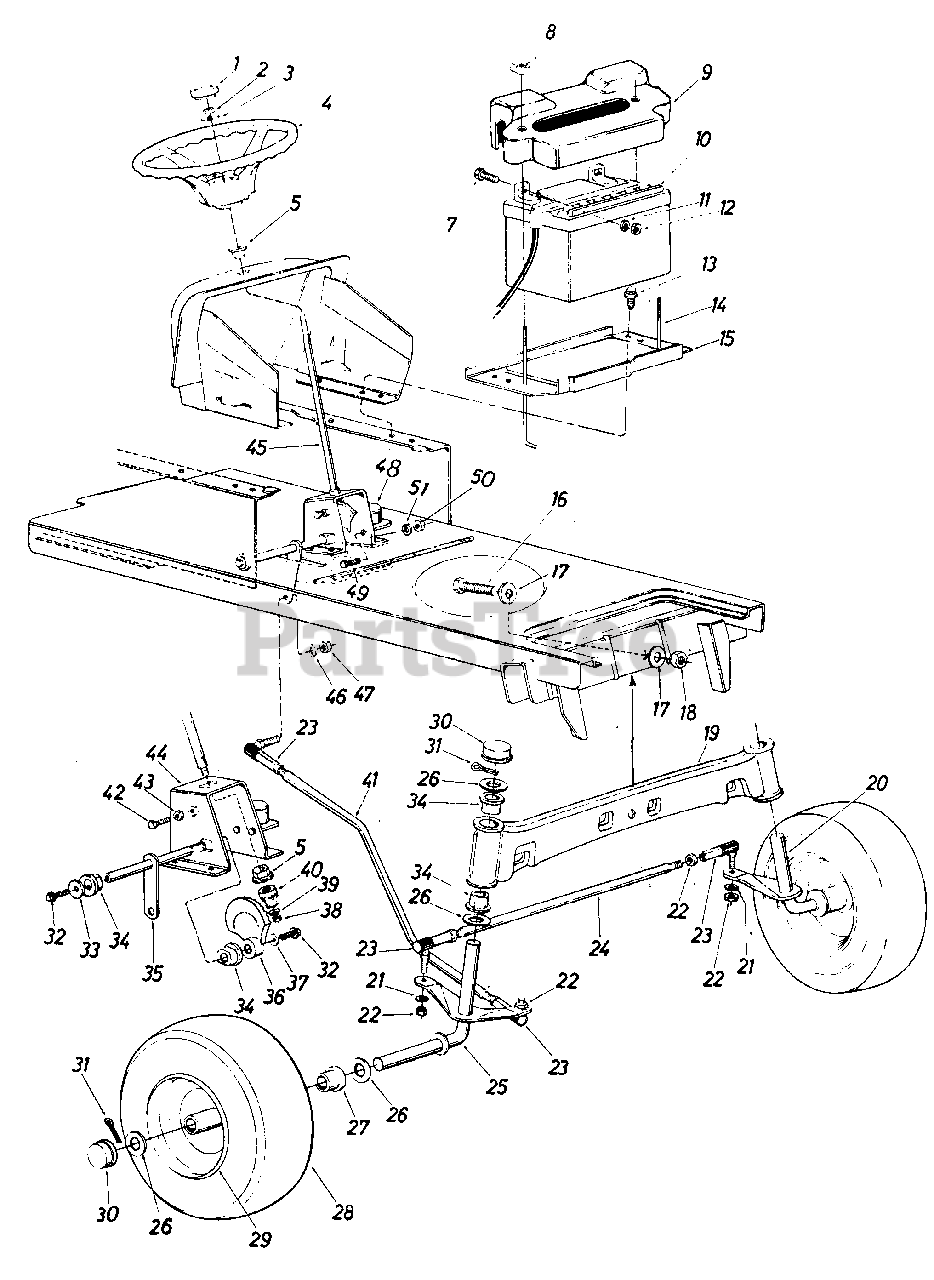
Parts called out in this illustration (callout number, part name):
1	Steering Wheel Cap
2	Hex Cent. L-Nut 5/16-18 Thd.
3	Bell-Wash. 5/16" I.D. x .87" O.D. x .060
4	Steering Wheel
5	Plastic Hex Bearing 5/8" I.D.
7	Hex Scr. 1/4-20 x .62" Lg.
8	Wing Nut Plastic 1/4-20 Thd.
9	Battery Cover
10	12-V Battery
11	L-Wash. 1/4" Scr.*
12	Hex Nut 1/4-20 Thd.*
13	Hex Thd. Rolling Scr. 1/4-20 x .50" Lg.
14	Battery Hold Down Rod
15	Battery Plate
16	Hex Scr. 5/8-18 x 2.50" Lg.*
17	Flat Wash. .66" I.D. x 2.25" O.D. x .17
18	Hex Cent. L-Nut 5/8-18 Thd.
19	Front Pivot Bar Ass'y.
20	Front Axle Ass'y. L.H.
21	L-Wash. 3/8" Scr.*
22	Hex Nut 3/8-24 Thd.*
23	Ball Joint Ass'y.
24	Tie Rod
25	Front Axle Ass'y. R.H.
26	Fl-Wash. .780 I.D. x 1.59 O.D.
27	Flange Bearing
28	Front Wheel Ass'y. Comp.
28	Front Wheel Tire Only
29	Front Wheel Rim Only
29	Air Valve
29	Grease Fitting
30	Dust Cover
31	Cotter Pin 5/32" Dia. x 1.00" Lg.*
32	Hex Scr. 3/8-24 x .75" Lg. Grade 5
33	Fl-Wash. 3/8 I.D. x 1.25 O.D. x .090
34	Flange Double "D" Brg. .753 I.D.
35	Steering Arm Shaft Ass'y.
36	Side Gear Steering
37	Bell-Wash. 3/8" I.D.
38	Hex Cent. L-Nut 5/16-24 Thd.
39	Fl-Wash. 5/16" I.D. x .62 O.D. x .059
40	Pinion Gear Steering
41	Drag Link
42	Hex Nylon Scr. 3/8-16 x 1.25 " Lg.
43	Hex Nut 3/8-16 Thd.*
44	Steering Gear Sup. Ass'y.
45	Steering Shaft
46	L-Wash. 3/8" Scr.*
47	Hex Nut 3/8-24 Thd.*
48	Solenoid
49	Hex Scr. 1/4-20 x .62" Lg.
50	Hex Nut 1/4-20 Thd.*
51	L-Wash. 1/4" Scr.*
